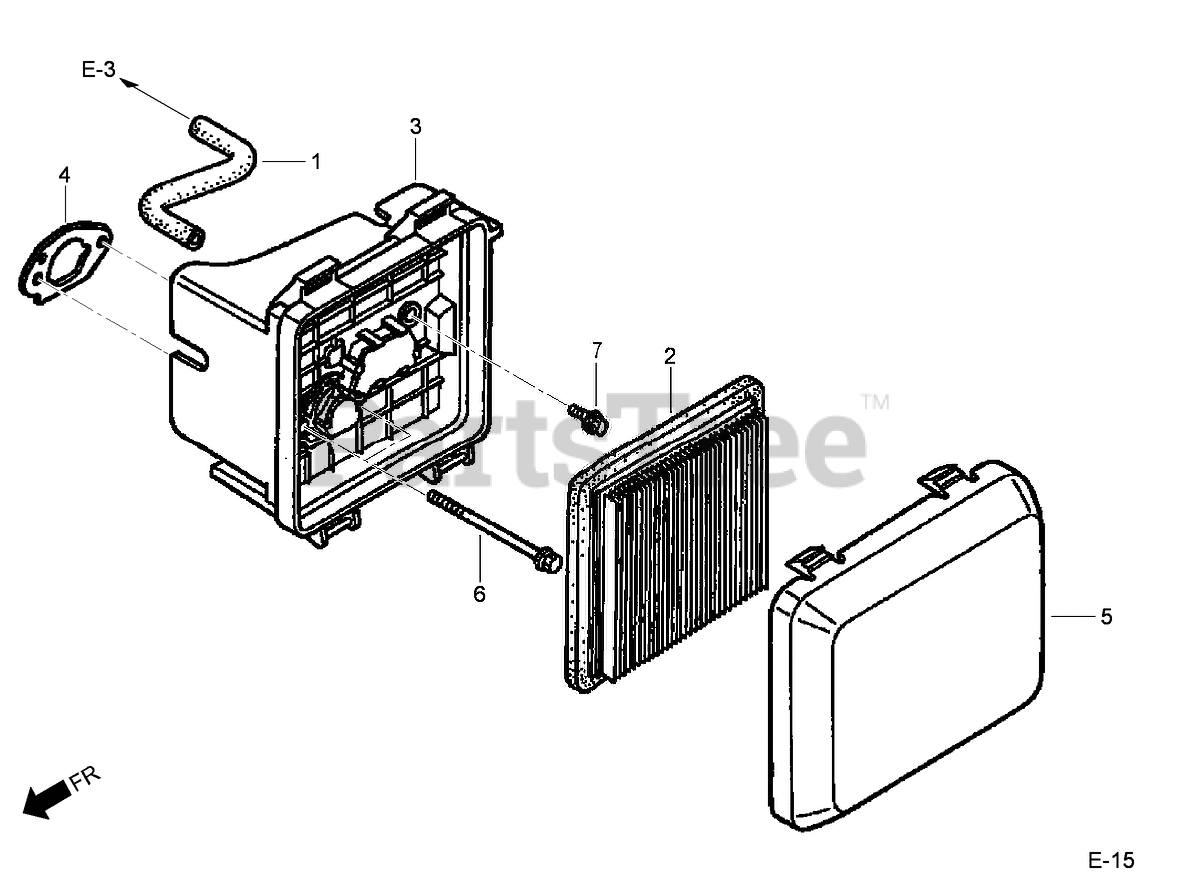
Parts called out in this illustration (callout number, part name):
1	TUBE-BREATHER
2	ELEMENT-CLEANER, AIR
3	AIR CLEANER CASE ASM (engine serial numbers up to 6624355)
3	AIR CLEANER CASE ASM
4	GASKET-CLEANER, AIR
5	COVER-CLEANER, AIR
6	BOLT-FLANGE (6X86) (C T200) (engine serial numbers up to 6349022)
6	BOLT, FLANGE (6X85) (C T200)
7	BOLT-FLANGE (6X14) (engine serial numbers up to 6624355)
